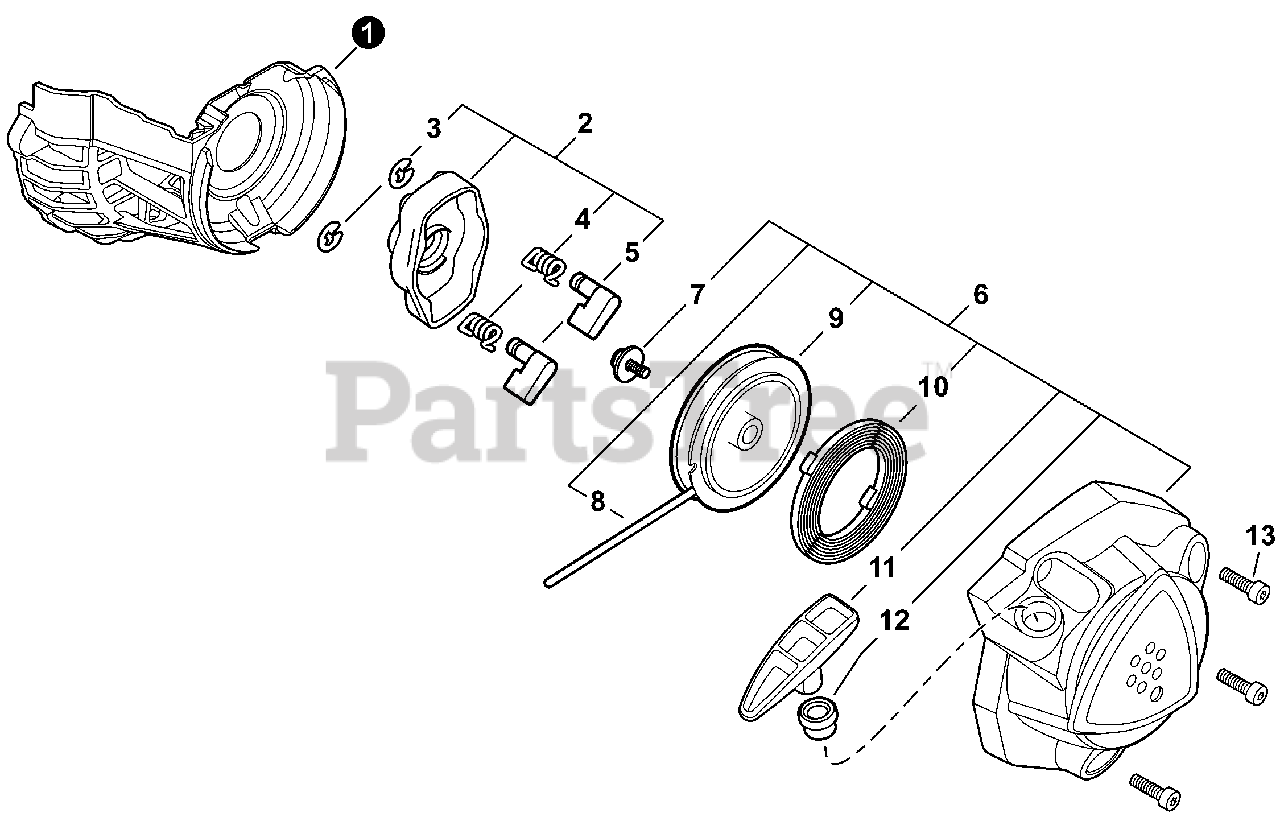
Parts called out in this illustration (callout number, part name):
1	SHIELD, DEBRIS
2	PAWL ASSY, STARTER
3	E-RING 4
4	SPRING, RETURN
5	PAWL, STARTER
6	STARTER ASSY
8	ROPE, STARTER
9	REEL, ROPE
10	SPRING, RECOIL
11	GRIP, STARTER
12	GUIDE, ROPE
13	BOLT, TORX 5×16
